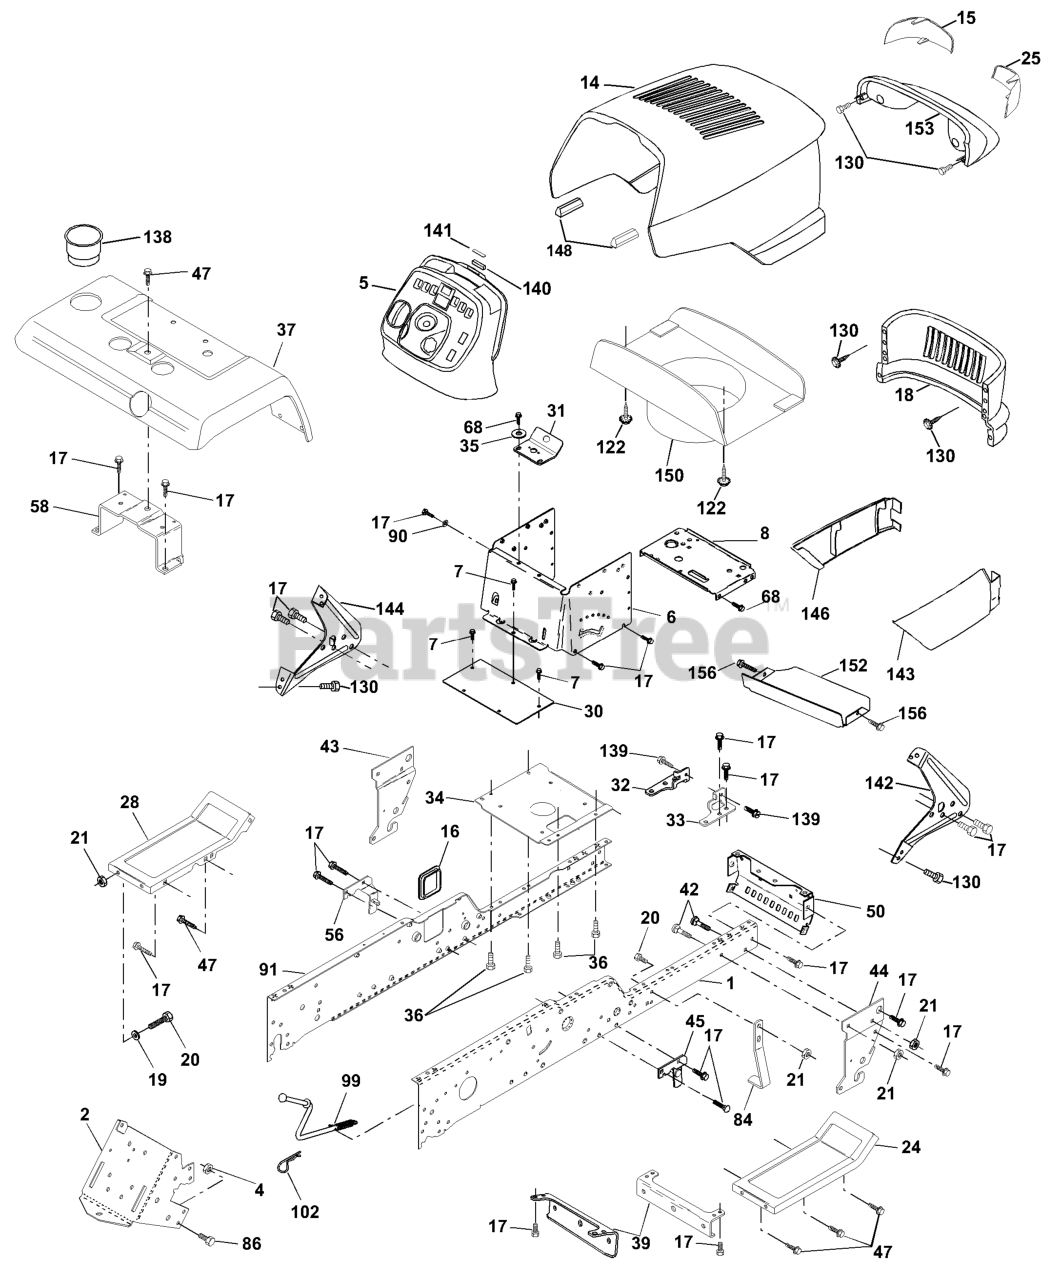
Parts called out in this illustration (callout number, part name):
1	RAIL, FRAME RH
2	DRAWBAR, GT
4	Nut, Lock Hex 7/16 Unc
5	DASH.STEALTH.YTGT.2CYL.BLK
6	DASH VGT, LOWER
7	SCREW
8	SUPPORT, BATTERY
14	HOOD ASM.
15	LENS RH
16	COVER ACCESS
17	SCREW 3/8-16X3/4
18	GRILLE
19	WASHER
20	BOLT
24	FOOTREST RH
25	LENS LH
28	FOOT REST LH
30	SADDLE.HYDRO.95
31	BRACKET SUPT 1-PC VGT STEERING
34	PLATE ASM ENG CHASSIS
35	WASHER
36	SCREW 5/16"
37	FENDER
39	BRACKET AXLE, FRONT
42	BOLT D
43	FRONT SUSPENSION BRKT LH
44	FRONT SUSPENSION BRKT RH
45	BRACKET SUSP RH
47	SCREW 3/8-16X1/2
50	BRACKET, CHASSIS FRONT
56	BRACKET ASM, SUSP CHASSIS
58	BRACKET ASM, FENDER
68	Screw, 5/16-18 x 1/2
84	MOWER STOP
86	BOLT
90	LOCKWASHER
91	RAIL, FRAME LH
99	ROD ASM, BYPASS
102	RETAINER M
122	SCREW.HEX.WS.HD.8-18 X 7/8
130	SCREW
138	CUPHOLDER
139	BOLT, SHOULDER 5/16-18
140	MAGNET STEALTH
141	STRIKER PLATE
142	BRACKET DASH STEALTH(R)
143	SKIRT GRILLE RH
144	BRACKET DASH STEALTH LH
146	SKIRT GRILLE LH
148	EXTRUSION BUMPER (3 2) (2 2)
150	DUCT HEAT HOOD
152	BROWNING SHIELD
153	LENS, HEADLIGHT BAR
156	SCREW 5/16"
